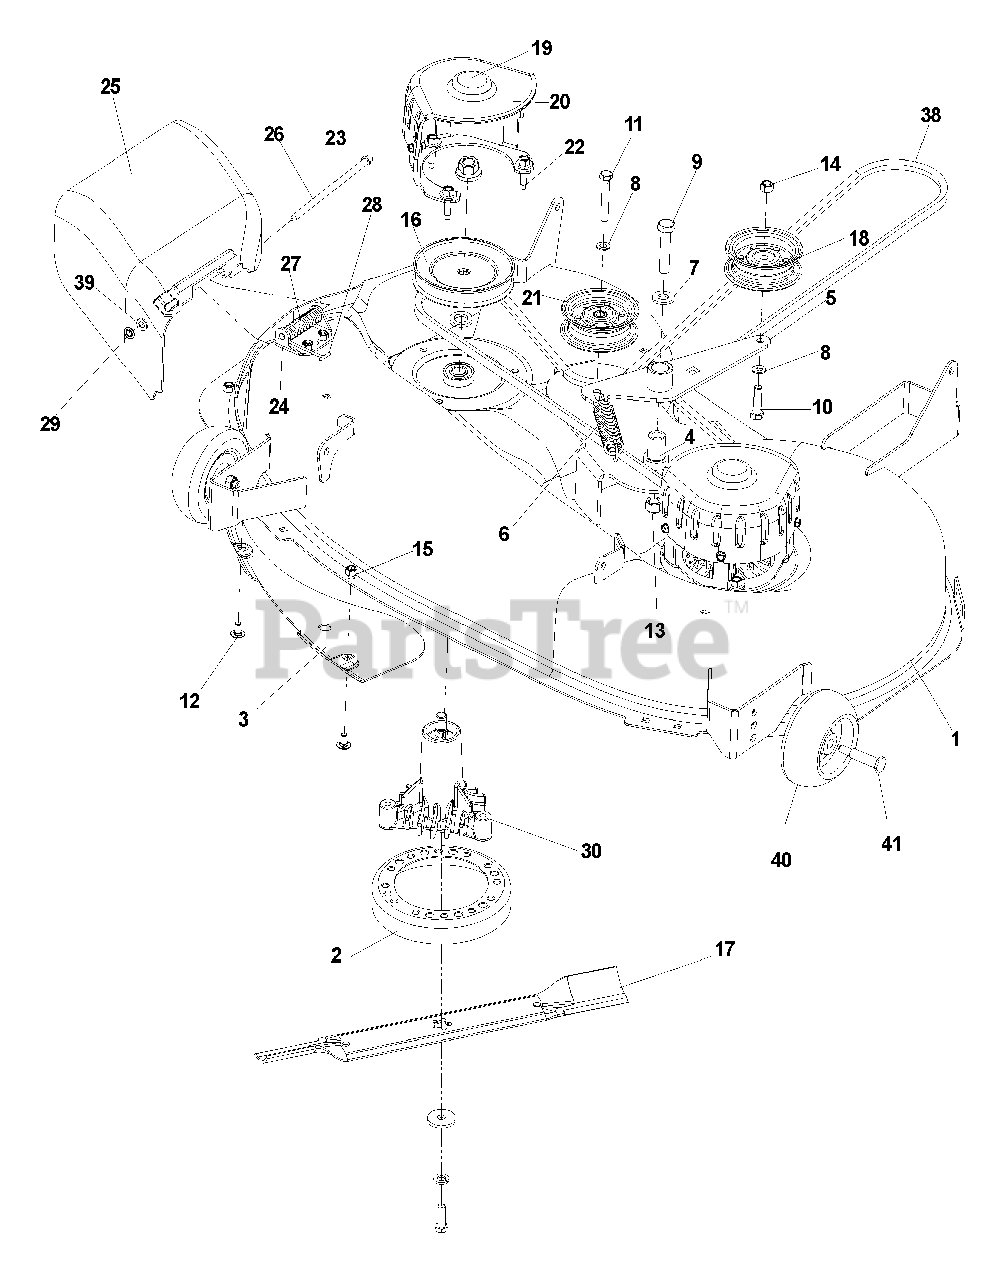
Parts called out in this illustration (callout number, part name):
1	DECK W/DECAL, 42"
2	STRIPPER, ROUND
3	BAFFLE, VORTEX 42"
4	IDLER SPINDLE
5	DECK IDLER ARM
6	TRACTION SPRING
7	WASHER, 1/2 SAE
8	WASHER, 3/8 SAE
9	HCS, 1/2-13 X 2 3/4, GR5
10	HCS, 3/8-16 X 1 1/2, GR5
11	HCS, 3/8-16 X 2 1/2, GR5
12	RHSNB, 5/16-18 X 5/8, GR5
13	NUT, 1/2C, NYLOC
14	NUT, 3/8C, NYLOC
15	NUT, 5/16C, NYLOC
16	PULLEY, MANDREL #707
17	BLADE, 42"
18	PULLEY, DECK IDLER
19	SPINDLE COVER
20	SPINDLE COVER ANCHOR
21	PULLEY , IDLER
22	SCREW, WASHER HEAD
23	SCREW, 1/4C X 5/8, SELF TAPPING
24	BRACKET, DEFLECTOR, MOWER 42"
25	SHIELD, 42"
26	ROD, HINGE
27	SPRING, TORSION, DEFLECTOR
28	CAP-SLEEVE
29	PUSHNUT
30	HOUSING, MANDREL, ASSY
38	BELT, 42" DECK
39	WASHER, 11/32 X 5/8 X 16GA
40	WHEEL, GAUGE
41	BOLT, SHOULDER
